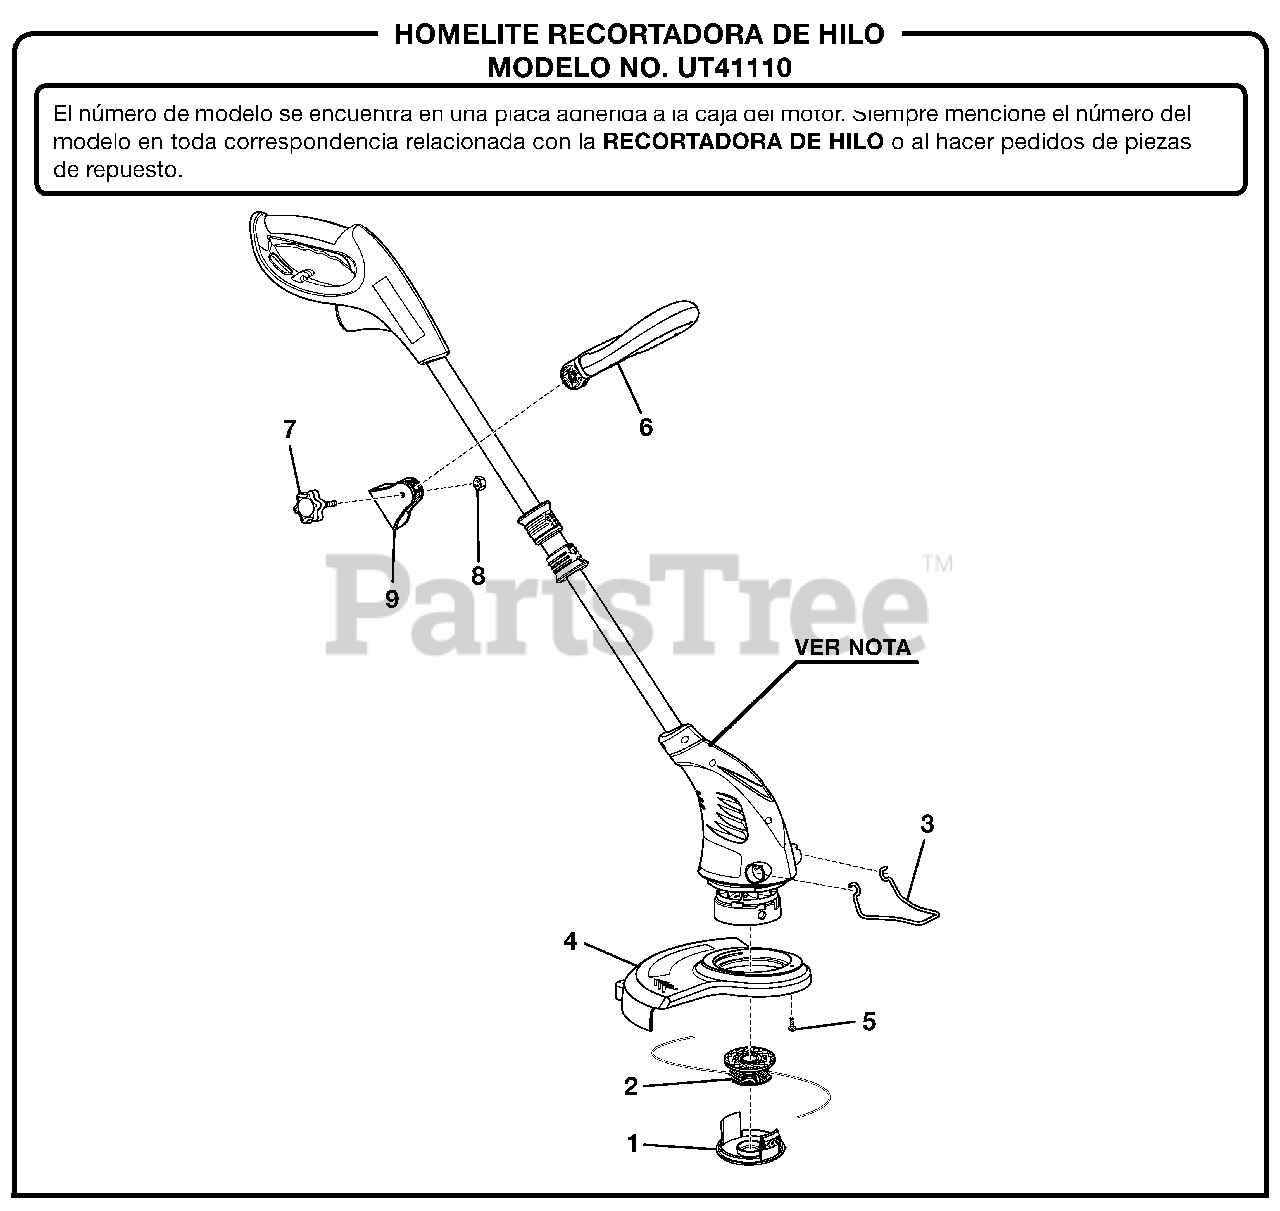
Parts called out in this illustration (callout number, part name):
1	Casquete de carrete
3	Protector de la Recortadora
4	Protector de la Fresa
5	Tornillo
6	Mango delantero
7	Tornillo de perilla
8	Tuerca Hex
9	Abrazadera
